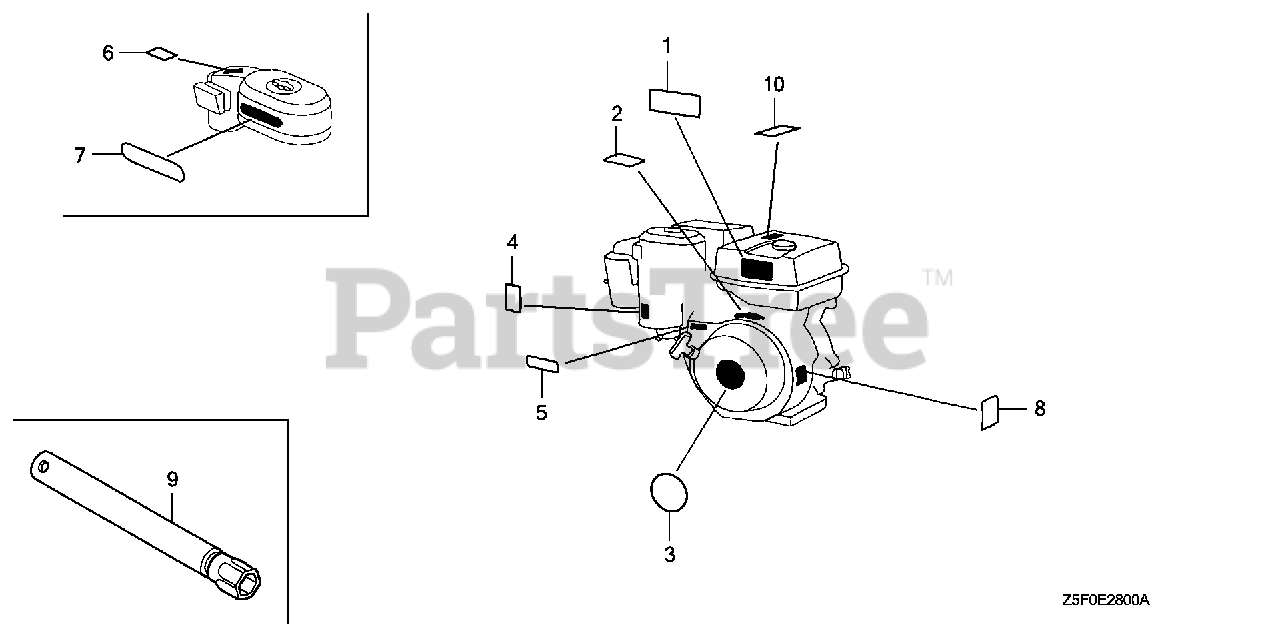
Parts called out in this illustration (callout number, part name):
3	EMBLEM (8. (HONDA)
3	EMBLEM (GX240)
4	MARK, CHOKE
9	WRENCH, SPARK PLUG
